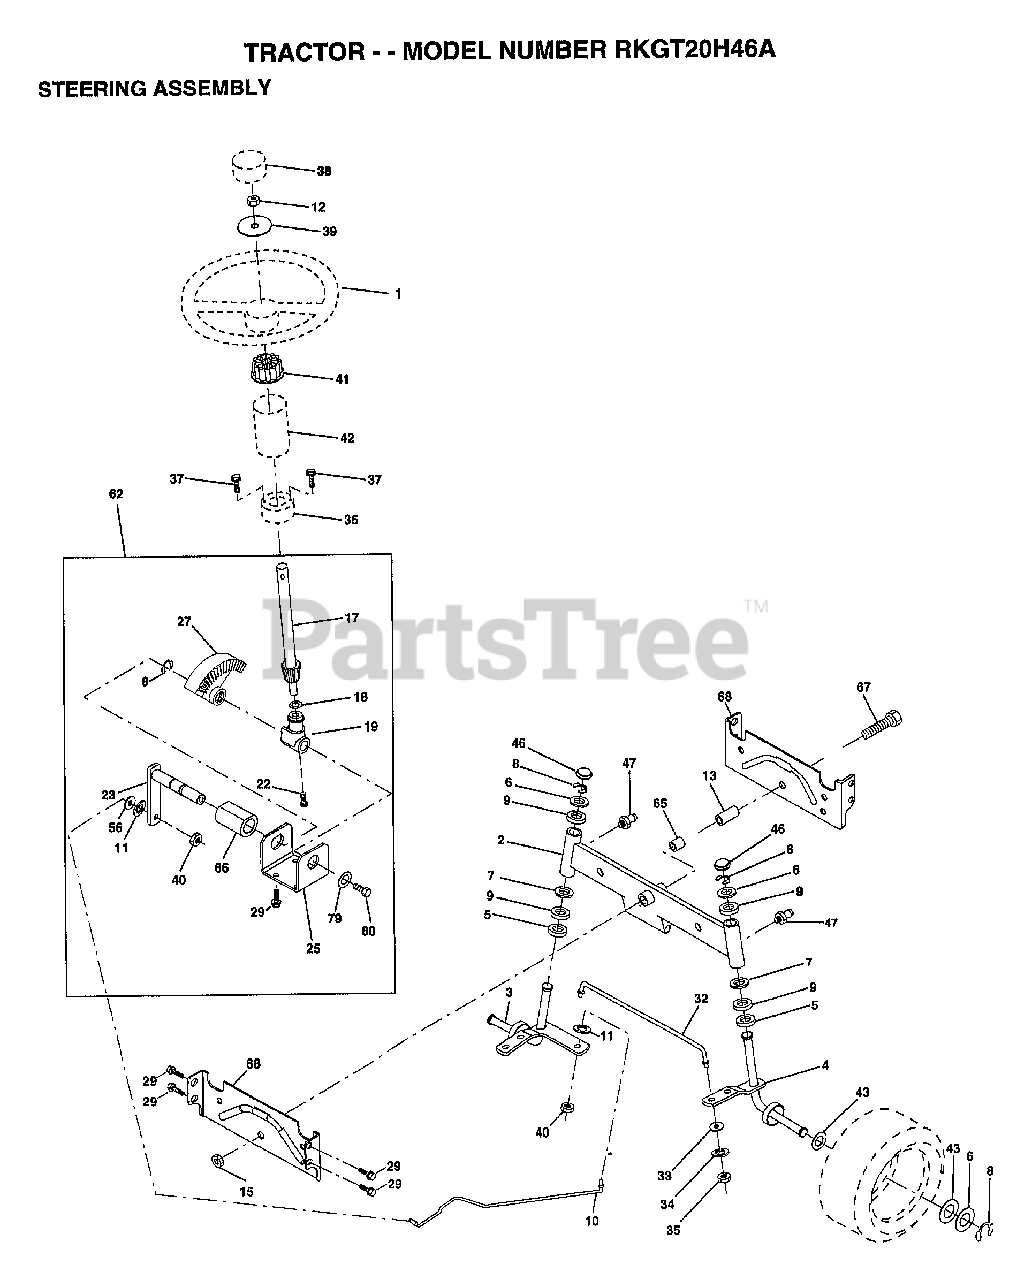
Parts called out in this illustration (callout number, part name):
2	AXLE ASM
3	SPINDLE.ASM.LH
4	"SPINDLE ASM,RH"
5	WASHER .T
6	WASHER
7	WASHER
8	RING
9	COL. SRTG. BEAR.
10	DRAGLINK-STAMPED
11	LOCKWASHER
13	BEARING AXLE
15	"NUT-LOC,FLANGE LT"
17	SHAFT ASM STEERNG
18	THRUST WASHER
19	SUPPORT.SHAFT.STEER
22	SCREW.HX.WSH.HD
23	SHAFT.ASM.PITMAN
25	BRKT-STEERING
27	GEAR SECTOR
29	SCREW
32	ROD.TIE.19.75
33	WASHER M
34	LOCKWASHER
35	NUT.LOCK.5/16-24
36	BUSHING.STRG.3/4
37	"SCREW-TT,10-32 FL"
38	"INSERT,STR WHEEL"
39	WASHER
40	GRIPCO NUT
41	ADAPTER LT
42	BOOT SHAFT STEER
43	WASHER
46	CAP
47	ZERK M
56	WASHER
62	KIT.STEER.ASM.LT
65	SPACER AXLE
66	"BEARING-ARM,PITMA"
67	BOLT
68	BRACE AXLE
79	WASHER
80	BOLT.HX.NYLON3/8-16X3/
